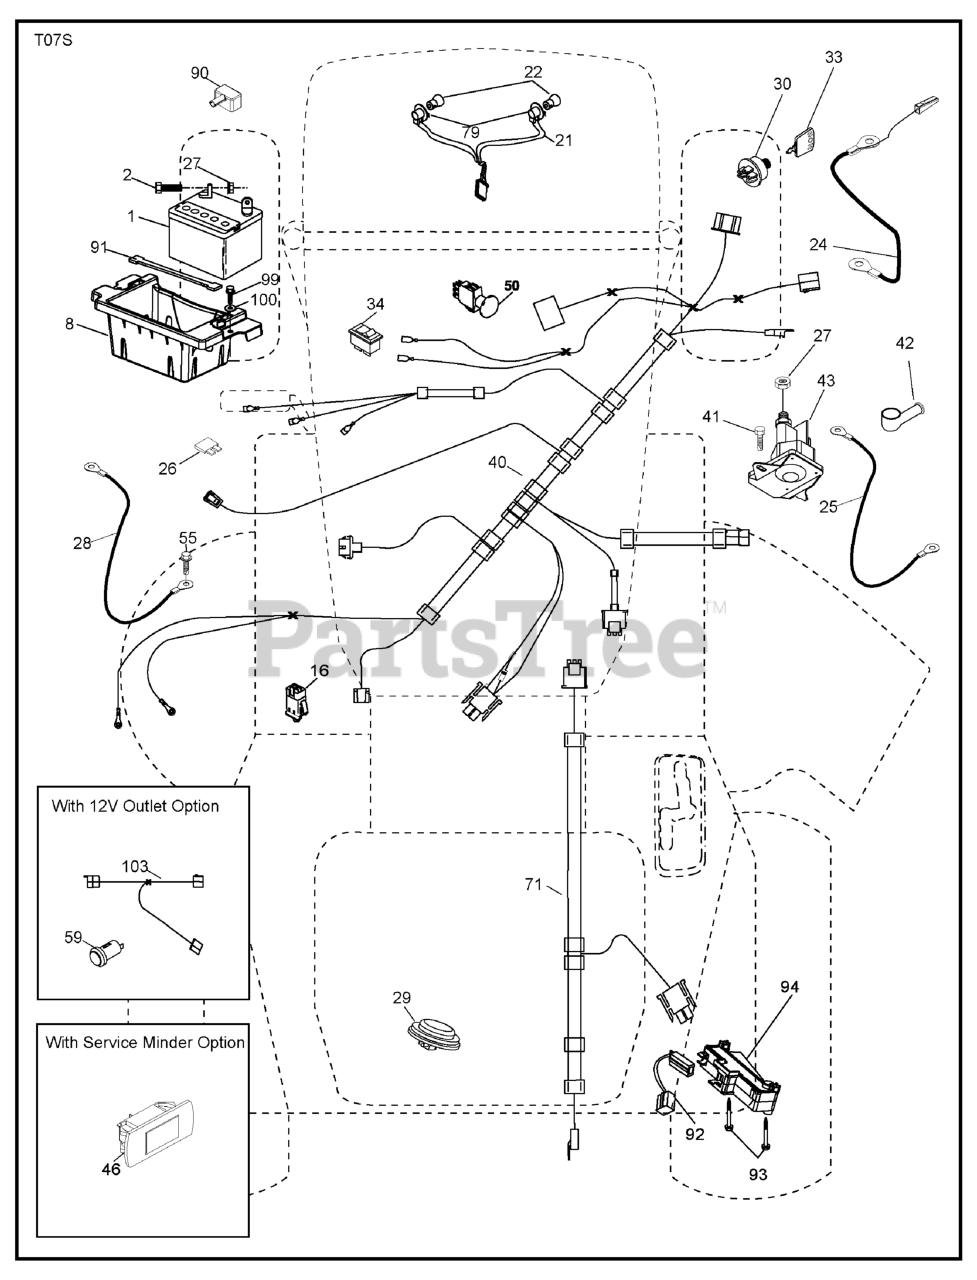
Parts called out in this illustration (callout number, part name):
1	Battery
2	Bolt Hex Head 1/4-20 x 3/4
8	Box Battery
16	Switch Interlock Push-In
21	Harness Socket Light w/4152J
22	Bulb Light
24	Battery Cable
25	Cable Starter
27	Nut Keps Hex 1/4-20 unc
28	Cable, Ground
29	Switch, Seat
30	Switch, Ign
33	Key/Chain
34	Switch Light/Reset
40	Harness Ign. Dash
41	Screw Thd Cut 1/4-20 x 1/2
42	Cover, Terminal
43	Solenoid
46	Gauge Hourmeter
50	** Switch, PTO
55	Screw Thdrol 5/16-18 x 3/4
71	Harness Chassis
79	Bulbholder Asm. Incandescent
90	Cover Terminal Battery
91	Strap Battery Mount Front
92	Harness Pigtail Console
93	Screw Plastite 10-14 x 2.0
94	Module Reverse
99	Screw Hexwsh Thdrol 1/4-20 x 3/4
100	Washer 9/32 x 7/8 x 16 Ga.
